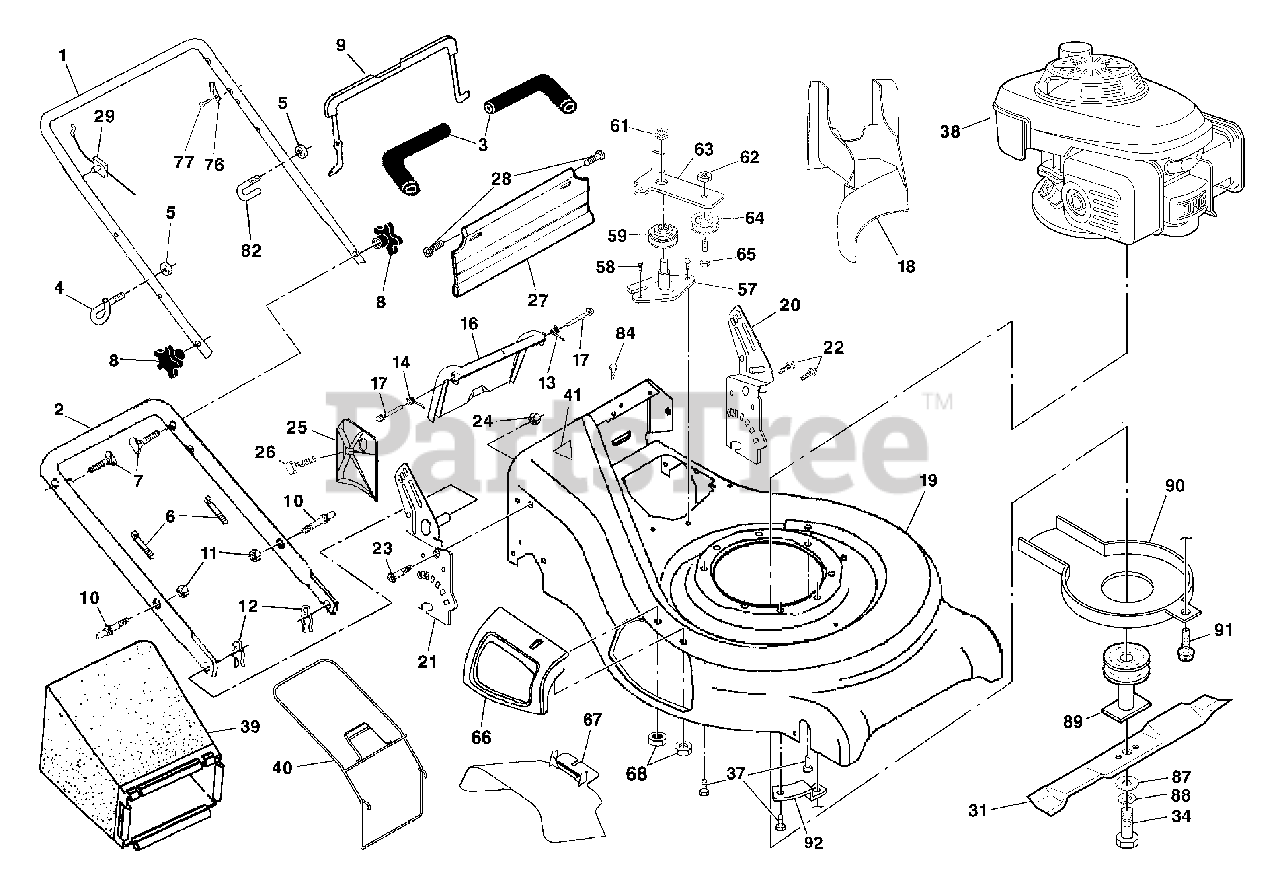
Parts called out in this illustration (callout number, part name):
1	Handle, Upper
2	Handle, Lower
3	Grip, Handle, Foam, Smooth
4	Guide, Rope, Side
5	Nut, Hex Lockwasher Insert 1/4-20
6	Wire, Tie
7	Bolt, Handle 5/16-18 x 1.75
8	Knob, Handle
9	Bail, Flat, Auto-Walk, Orange
10	Bolt, Carriage
11	Nut, Hex, Centerlock 5/16-18 UNC
12	Cotter, Hairpin
13	Spring, Rear Door, LH
14	Spring, Rear Door, RH
16	Rear Door Assembly
17	Bolt, Rear Door
18	Plug, Mulcher
19	Kit, Housing
20	Handle Bracket Assembly, LH
21	Handle Bracket Assembly, RH
22	Screw, Hex Washer Head
23	Bolt, Hex Head 5/16-18 x 5/8
24	Nut, Hex, with Lock Washer Insert 5/16-18
25	Baffle, Side
26	Screw 12 x 5/8
27	Skirt, Rear
28	Screw, Hinge 1/4-20 x 1.25
29	Engine Zone Control Cable
31	Blade, 21"
34	Screw, Hex Head 3/8-24 x 1.38
37	Bolt, Engine
40	Frame, Grassbag
41	Danger Decal
57	Bracket Assembly
59	Pulley Assembly, V-Groove
61	Flange Nut
62	Locknut
63	Idler Arm
64	Idler Pulley
65	Shoulder Bolt
66	Mulcher Door Assembly
67	Deflector, Discharge
76	Bracket, Upstop
87	Washer, Hardened
88	Lockwasher, Helical Spring 3/8
89	Blade Adapter / Pulley
90	Debris Shield
91	Screw
92	Mounting Bracket, Debris Shield
